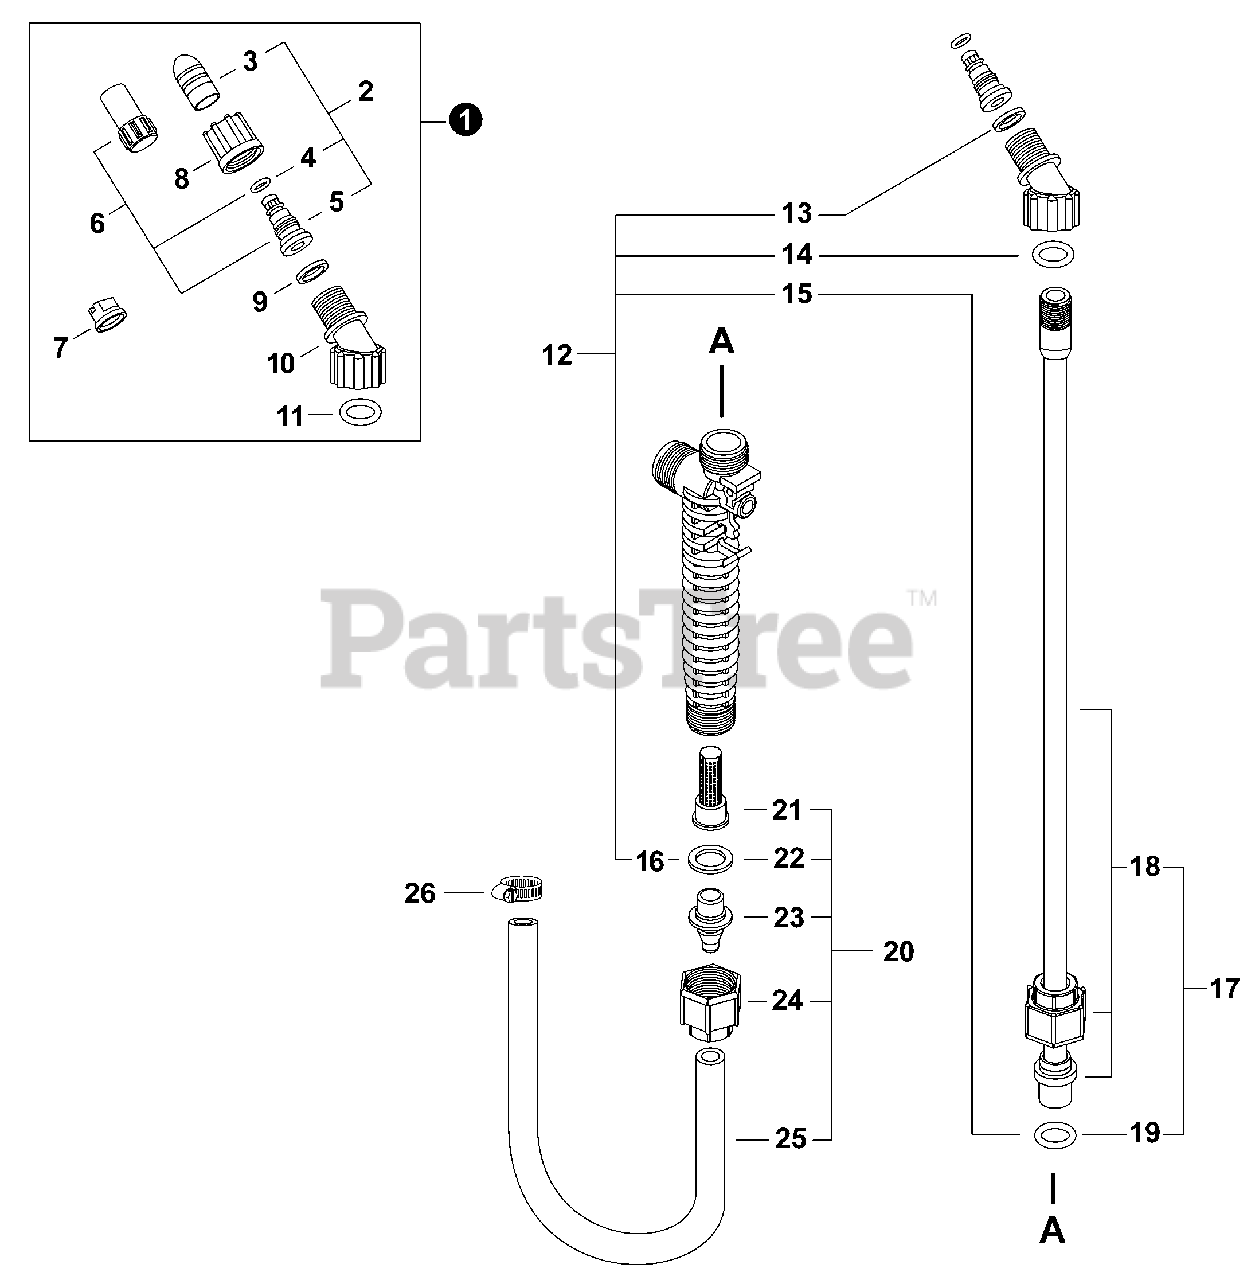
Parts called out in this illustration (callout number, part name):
1	NOZZLE KIT
2	NOZZLE KIT, BRASS
3	CAP, NOZZLE - BRASS
4	O-RING, NOZZLE
5	BODY, NOZZLE
6	NOZZLE KIT, PLASTIC
7	NOZZLE, FLAT FAN
8	NUT, NOZZLE
9	GASKET, NOZZLE
10	ELBOW, NOZZLE
11	O-RING, ELBOW
12	GASKET KIT, WAND
13	GASKET, NOZZLE
14	O-RING, ELBOW
16	GASKET, ADAPTER
17	WAND ASSY, PLASTIC
18	WAND, PLASTIC
20	HOSE KIT
21	FILTER, SPRAY GUN
22	GASKET, ADAPTER
23	ADAPTER, HOSE - BLACK
24	NUT, HOSE
26	CLAMP, HOSE
